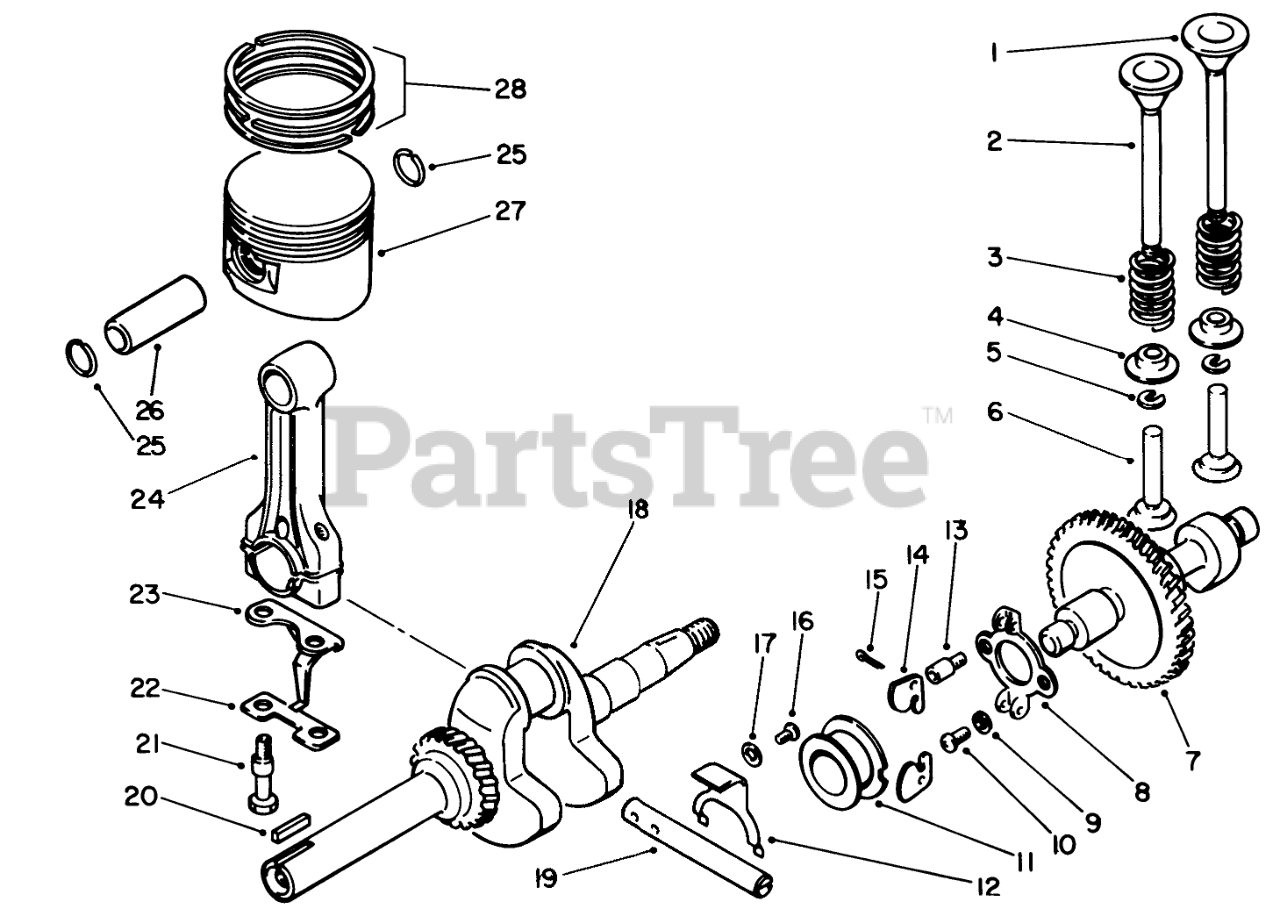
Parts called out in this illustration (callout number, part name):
1	VALVE, INTAKE
2	VALVE, EXHAUST
3	Spring-Valve
4	Retainer-Spring
5	Cotter-Valve
6	TAPPET
7	Cam Shaft
8	BRACKET
9	Washer
11	Spacer
12	SHIFT PLATE
14	BRACKET
15	Cotter Pin
16	SCREW
17	Washer
18	Crankshaft Assembly
19	SHAFT-THROTTLE TURN
22	LOCK PLATE
23	Plate-Splasher
24	Connecting Rod Assembly (Incl.Ref. #21-23)
25	CIRCLIP
26	Pin Piston
27	Piston Std.
28	Ring Set-Piston Std.
